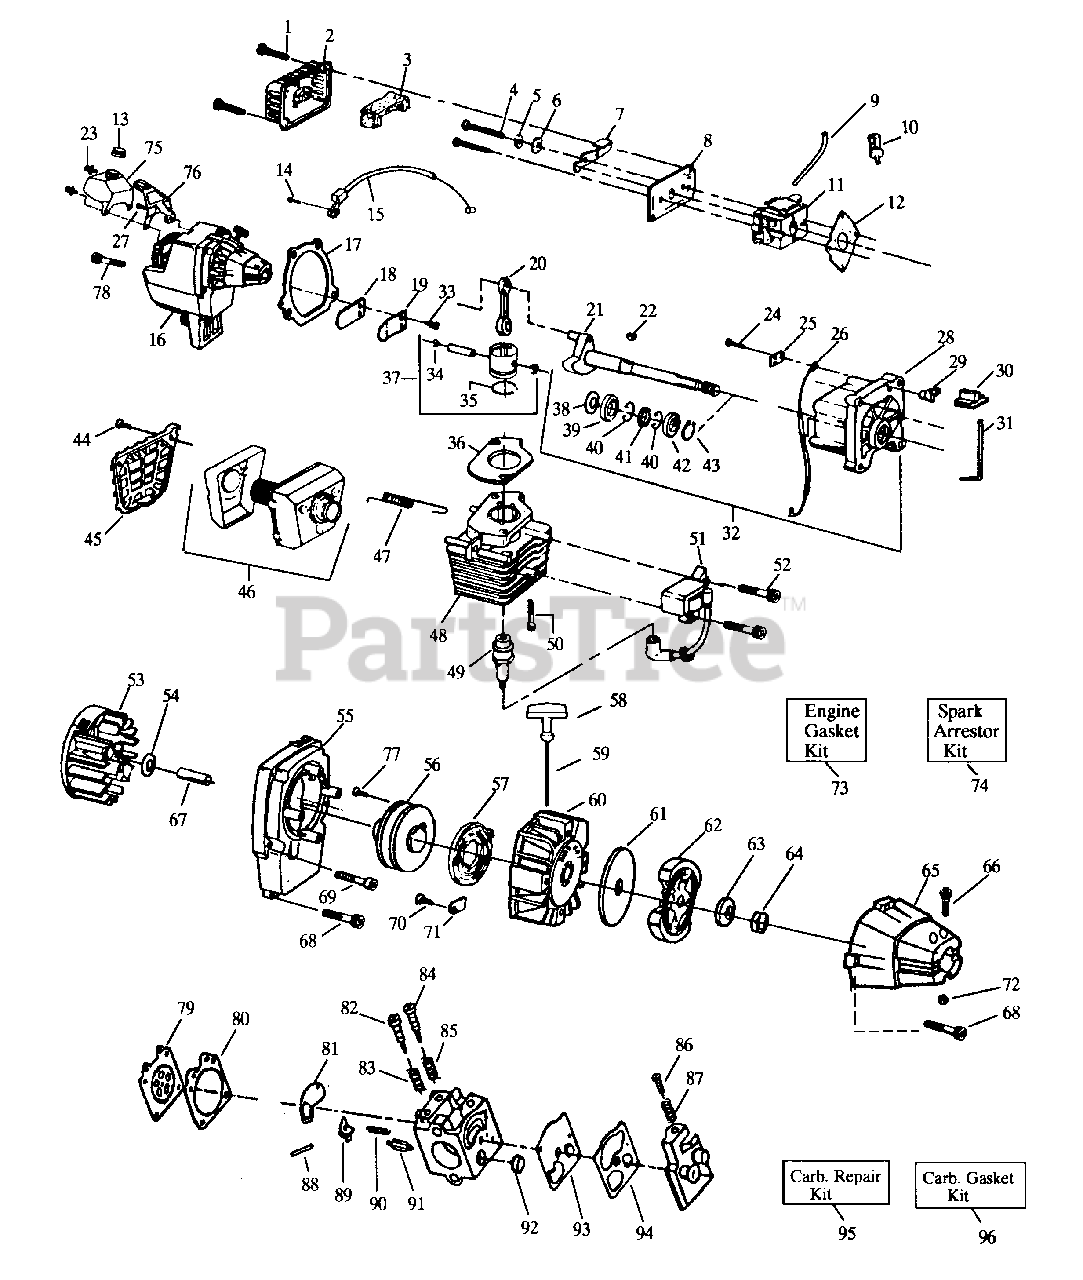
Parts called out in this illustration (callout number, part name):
2	Air Filter Cover
3	Air Filter
5	Spacer
6	Wave Washer
7	Choke Shutter
8	Air Filter Plate
9	Fuel Line
10	Fuel Pick-up Ass'y.
11	Carburetor
12	Carburetor Gasket
13	Fuel Cap Ass'y.
15	Throttle Cable Ass'y.
17	Crankcase/Shroud Gasket
19	Reed Stop
20	Connecting Rod Ass'y.
21	Crankshaft Ass'y.
22	Flywheel Key
25	Switch Insulator
26	Lead Wire
27	Screw
28	Crankcase Ass'y.
29	Switch Ramp
30	Switch Button
31	Switch Spring
32	Crankcase & Crankshaft Assy.
34	Piston Pin Retainer
35	Piston Ring
36	Cylinder Gasket
37	Piston Kit
39	Inner Bearing
40	Retaining Ring
41	Crankshaft Seal
42	Outer Bearing
43	Crankshaft Retaining Ring
45	Muffler Guard
46	Muffler Kit
47	Muffler Attachment Spring
48	Cylinder
49	Spark Plug
51	Ignition Module Kit
52	Screw
53	Flywheel Ass'y.
54	Washer
55	Fan Housing
56	Starter Pulley
57	Starter Spring
58	Starter Handle
59	Rope Kit
60	Pulley Housing Ass'y.
61	Clutch Washer
62	Clutch Ass'y. Kit
65	Clutch Housing
71	Retainer
73	Engine Gasket Kit (Inc. 12,17,36)
74	Spark Arrestor Kit
75	Fuel Tank Ass'y.
76	Fuel Tank Mtg. Bracket
77	Screw
79	Metering Diaphragm
80	Metering Diaphragm Gasket
81	Circuit Plate Gasket
82	Hi Speed Needle
83	Hi Speed Needle Spring
84	Idle Needle
85	Idle Needle Spring
86	Idle Speed Screw
87	Idle Speed Spring
88	Metering Lever Pin
89	Metering Lever
90	Metering Lever Spring
91	Inlet Needle Valve
92	Inlet Screen
93	Pump Diaphragm
94	Pump Gasket
95	Carb. Kwik Repair Kit
96	Carb. Gasket/Diaphragm Kit
